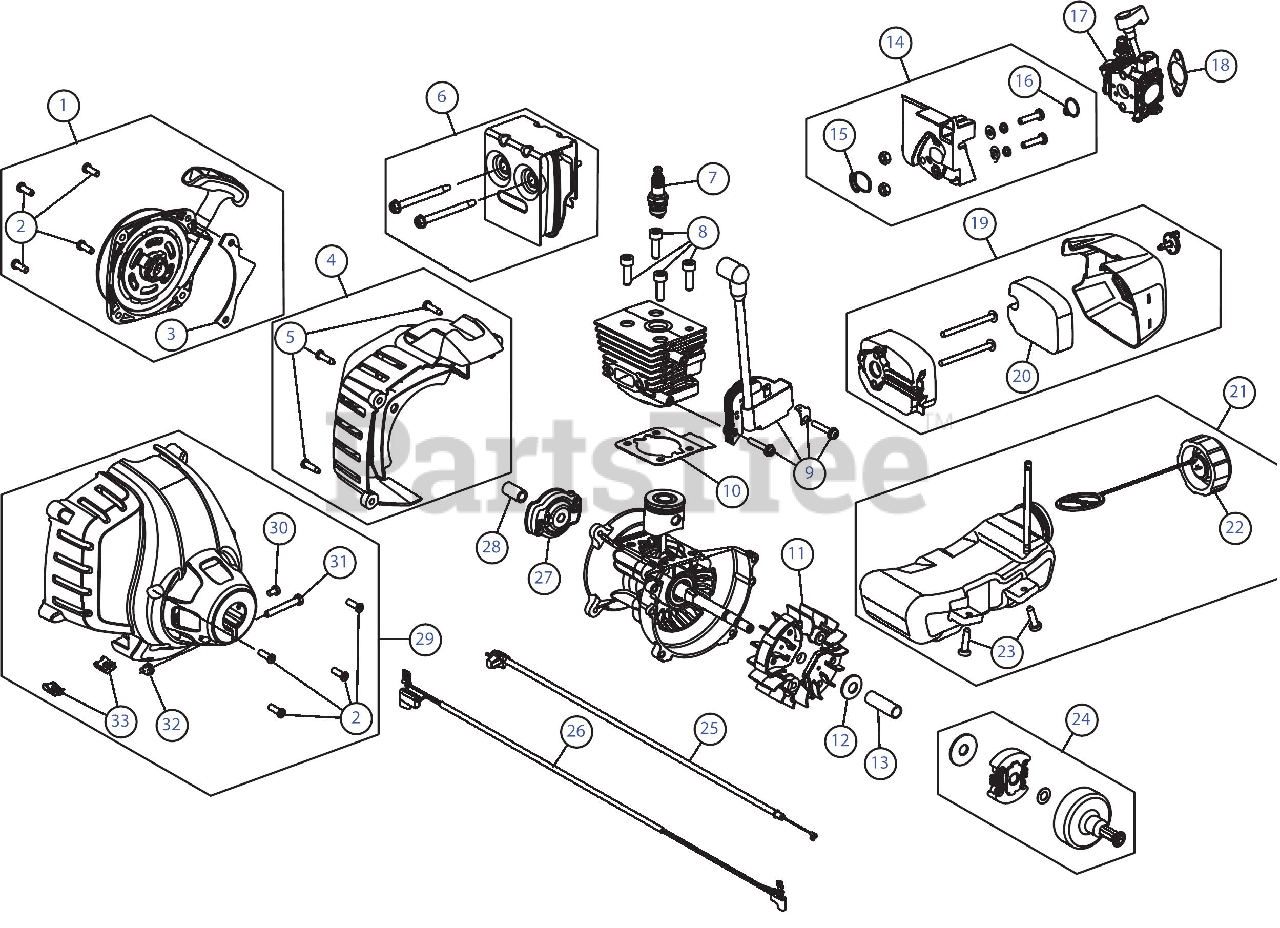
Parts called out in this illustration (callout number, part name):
1	Starter Assembly (Incl. 2 & 3)
2	Starter Screw
3	Starter Assembly Guard (Incl. 2)
4	Rear Engine Cover (Incl. 5)
5	Cover Screw
6	Muffler Assembly
7	Spark Plug
8	Cylinder Bolt
9	Module Assembly
10	Cylinder Gasket
11	Flywheel Assembly
14	Insulator Assembly (Incl. 15 & 16)
15	Insulator O-Ring
16	Carburetor O-Ring
17	Carburetor
18	Carburetor Gasket
19	Air Cleaner Assembly (Incl. 20)
20	Air Cleaner Filter
21	Fuel Tank Assembly (Incl. 22 & 23)
22	Fuel Tank Cap
23	Fuel Tank Screw
24	Clutch Assembly
25	Throttle Cable
26	Lead Wires
27	Pawl Assembly
29	Clutch Cover Assembly (Incl. 2, 30 - 33)
30	Anti-rotation Screw
31	Clamp Screw
32	Clamp Nut
33	U-shaped Nut
